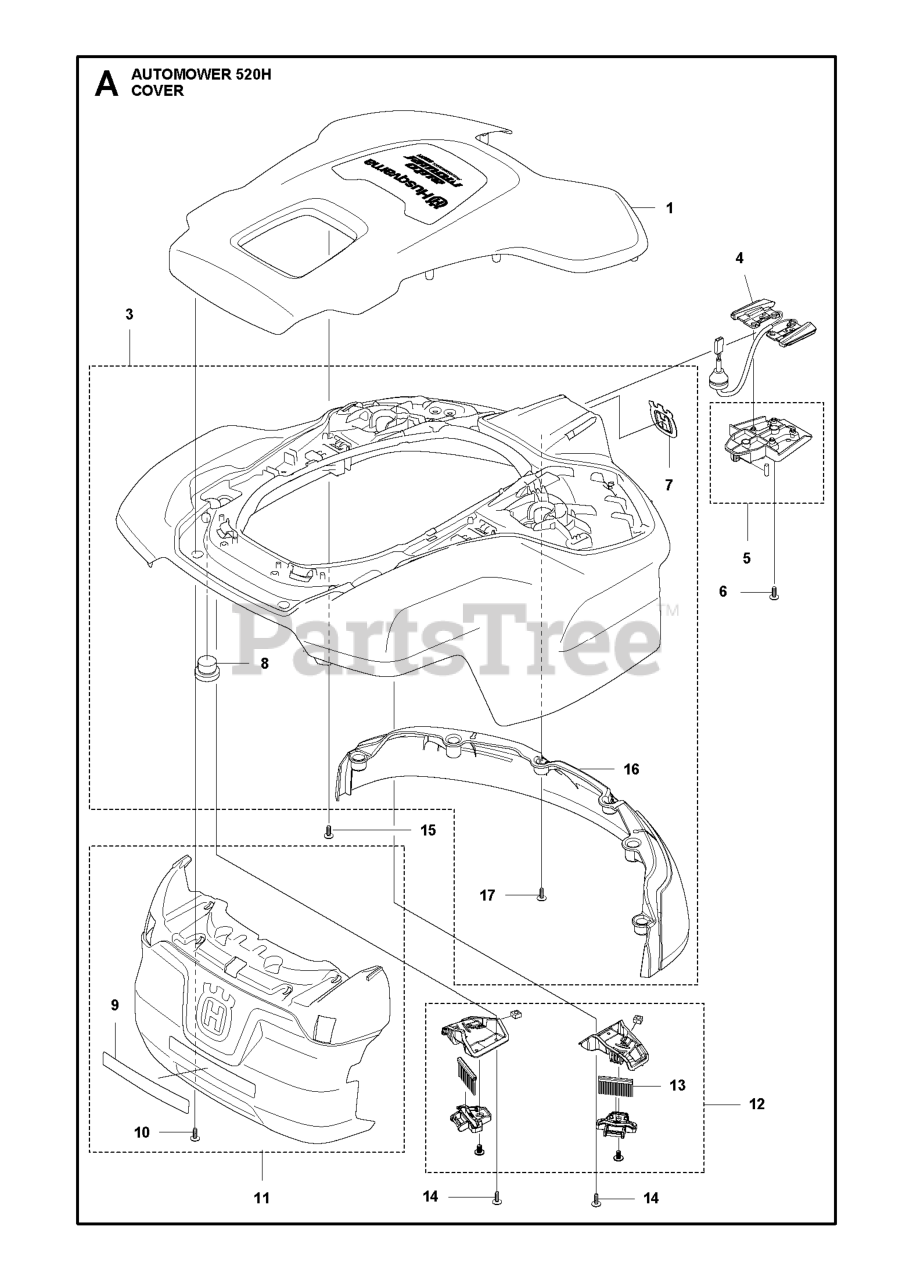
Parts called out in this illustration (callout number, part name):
1	TOP COVER
3	BODY ASSY 430XH, 450XH
4	CABLE ASSY CHARGING PLATE
5	HOLDER ASSY 430XH, 450XH
6	SCREW 14MM
7	DECAL HUSQVARNA CROWN HEIGHT 5
8	CAP SNAPLOC
9	LABEL WARNING P15
10	SCREW ITXPANT
11	BUMPER ASSY 430XH,450XH,550H
12	BRUSH KIT 430/450
13	WHEEL BRUSH REFILL KIT
14	SCREW ITXPANT
15	SCREW ITXPANT
16	BUMPER FRONT
17	SCREW ITXPANT
